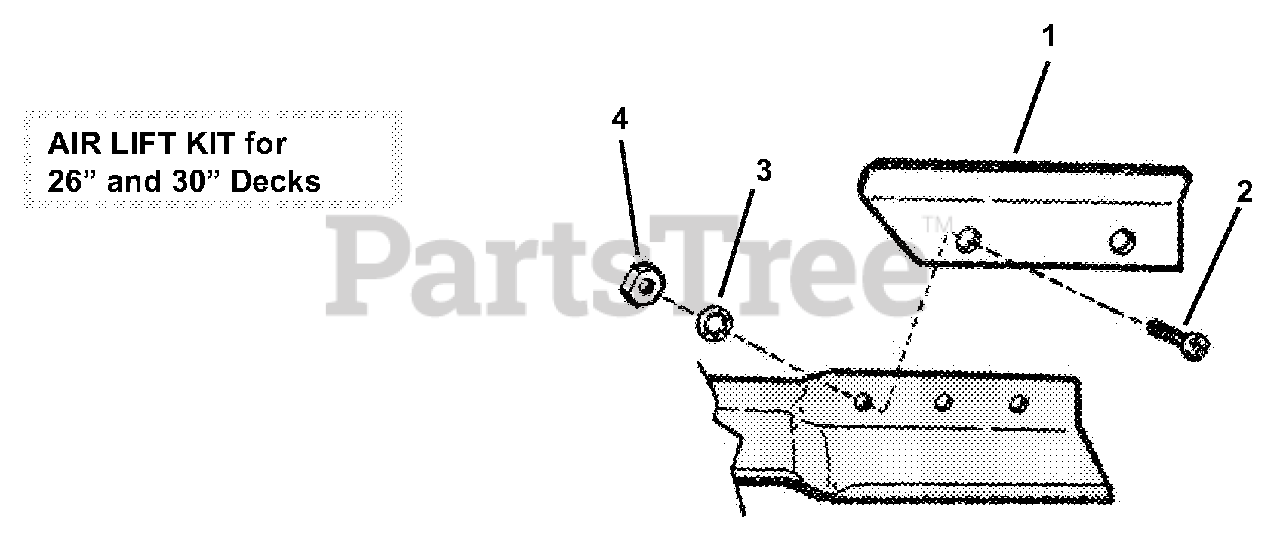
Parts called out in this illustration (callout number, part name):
1	AIR LIFT, 26" & 30"
2	SCREW, 5/16-24 Machine
3	WASHER, 5/16" Internal Tooth Lock
4	NUT, 5/16-24 Hex
